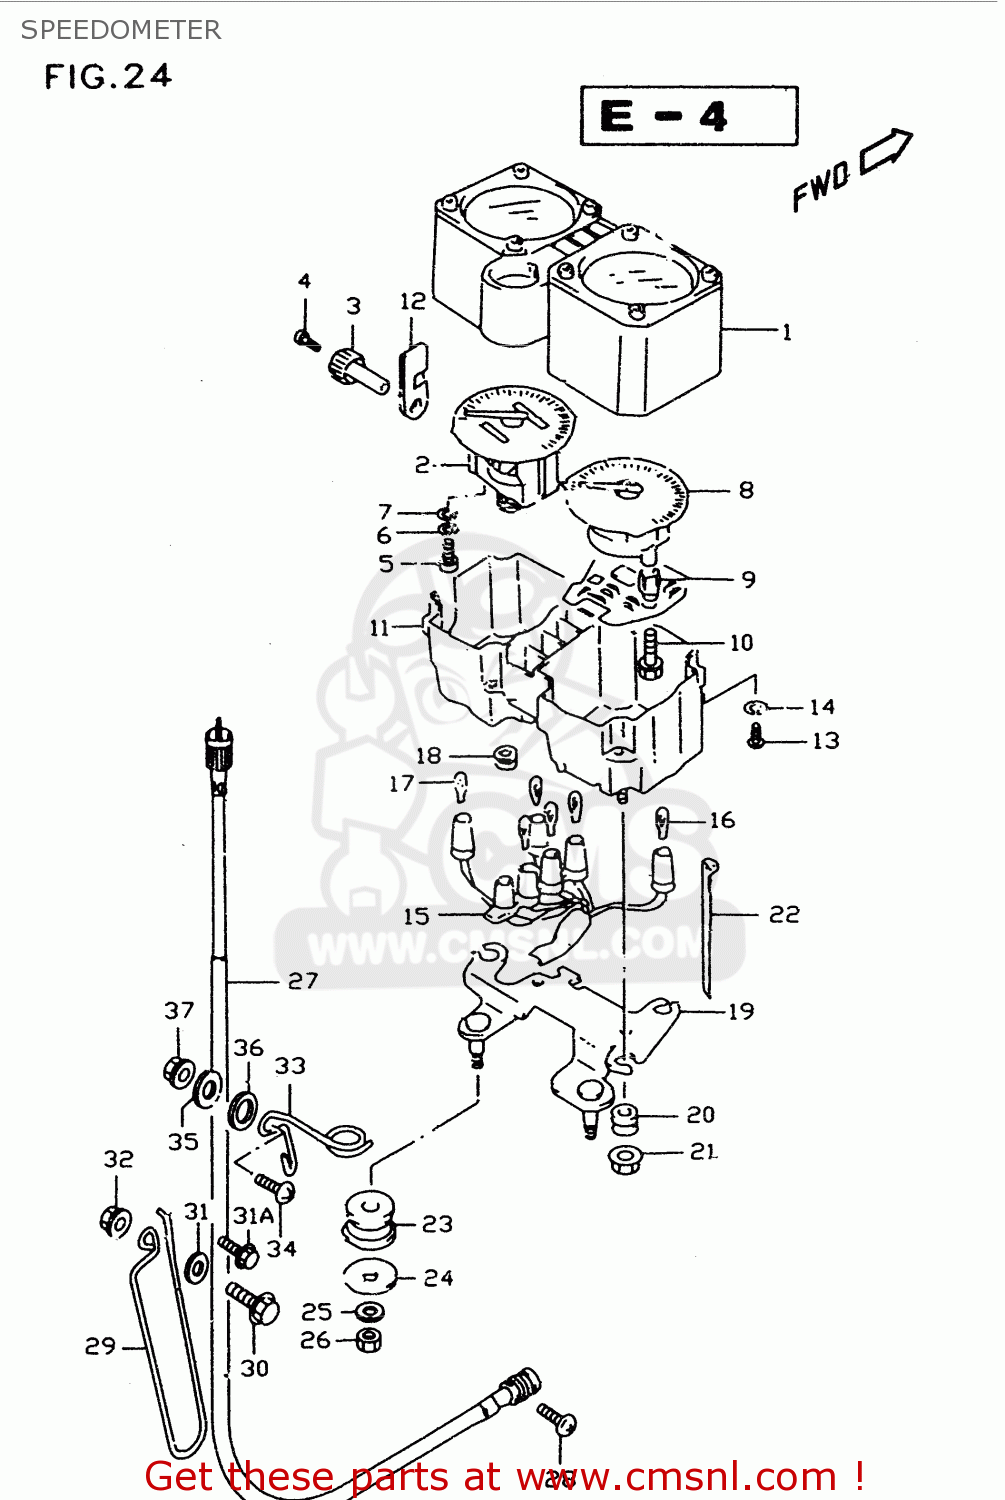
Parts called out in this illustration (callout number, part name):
1	HOOD,METER
2	SPEEDOMETER
3	KNOB,TRIP
4	SCREW,TRIP KNOB
5	SCREW
6	WASHER,LOCK
7	WASHER
8	TACHOMETER
9	SPACER
10	SCREW
11	CASE,METER
12	CUSHION,METER
13	SCREW
14	WASHER,LOCK
15	SOCKET,METER
16	BULB(12V3W,WB371,T7)
17	BULB(12V1.7W,WB372,T7)
18	CAP
19	BRACKET
20	CUSHION,METER
21	NUT
22	CLAMP(L:97)
23	CUSHION,METER BRACKET
24	WASHER(8.5X28X1.6)
25	WASHER,LOCK
26	NUT
27	CABLE ASSEMBLY,SPEEDOMETER
28	SCREW
29	GUIDE,METER CABLE NO.2
30	BOLT
31	WASHER(6.5X20X1.6)
31A	BOLT(6X20)
32	NUT
33	GUIDE,SPEEDOMETER CABLE
34	SCREW
35	WASHER
36	WASHER
37	NUT 6MM
